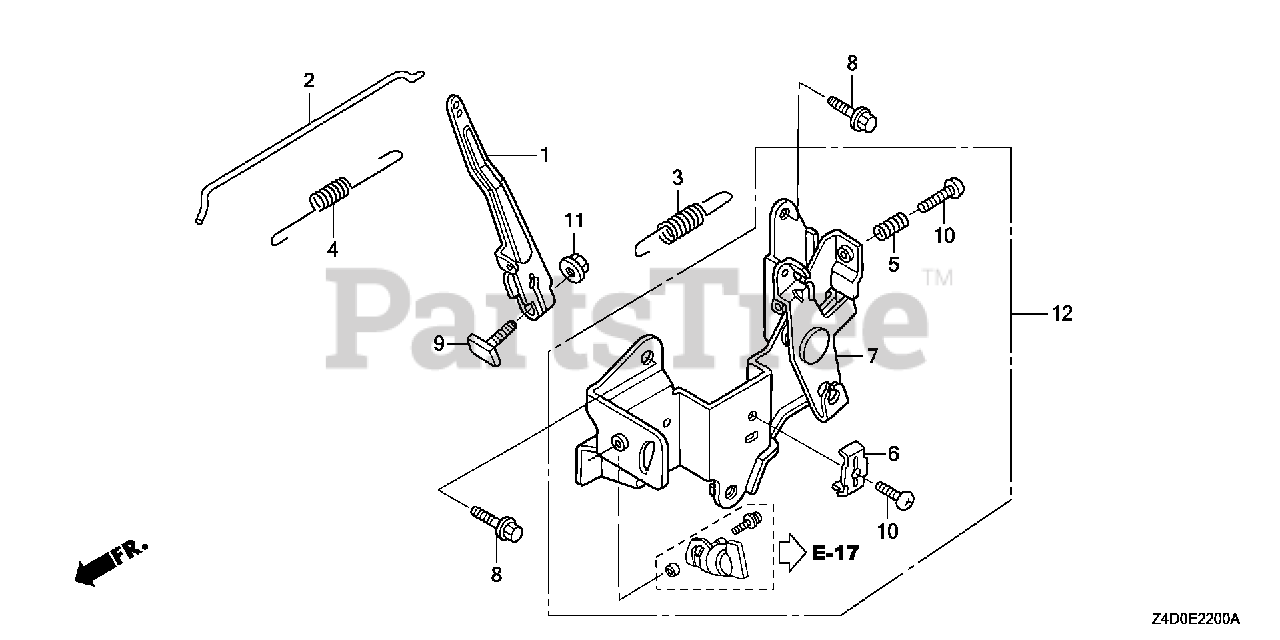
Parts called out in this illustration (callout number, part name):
1	ARM, GOVERNOR
2	ROD, GOVERNOR
3	SPRING, GOVERNOR
4	SPRING, THROTTLE RETURN
5	SPRING, CONTROL ADJUSTING
6	HOLDER, CABLE
7	BASE, CONTROL
8	BOLT, FLANGE (5X12)
9	BOLT, GOVERNOR ARM
10	SCREW, PAN (5X20)
11	NUT, FLANGE (6MM)
12	CONTROL ASSY.
